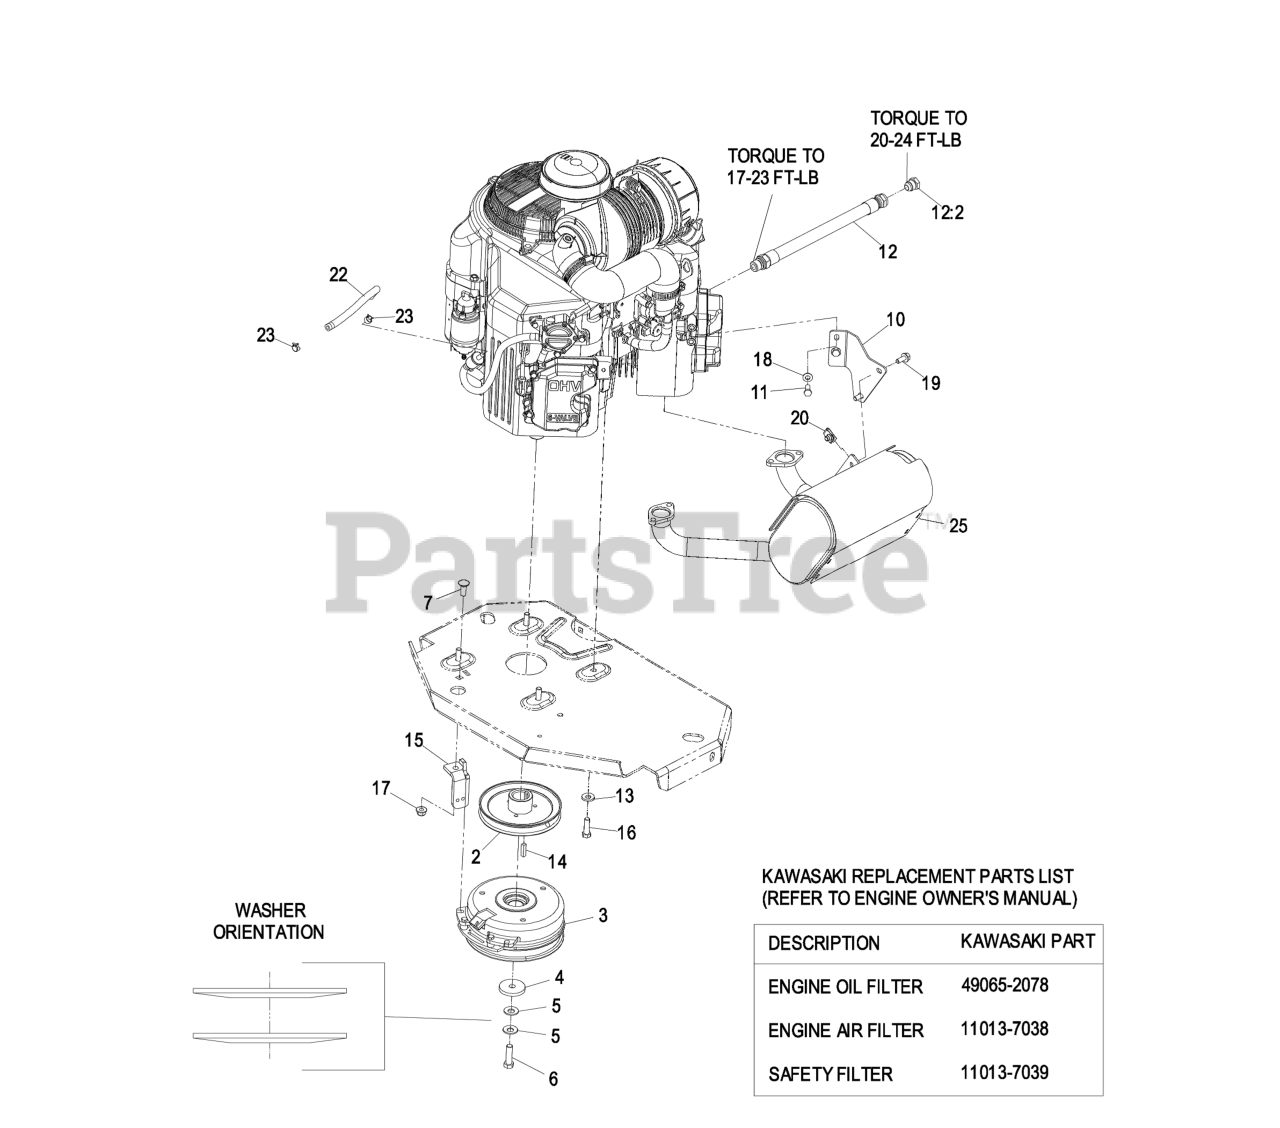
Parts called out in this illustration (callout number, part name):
2	SHEAVE
4	WASHER-CLUTCH
5	WASHER-SPRING
6	SCREW-HH 7/16-20 X 1 1/2 W/LOCTITE
7	SCREW-CARR
11	SCREW-HH
13	WASHER-BELLEVILLE
15	ANCHOR-CLUTCH
16	SCREW-HH
17	NUT-HF, NI
18	WASHER-SPRING
19	SCREW-HHF
22	HOSE-FUEL
23	CLAMP-HOSE
